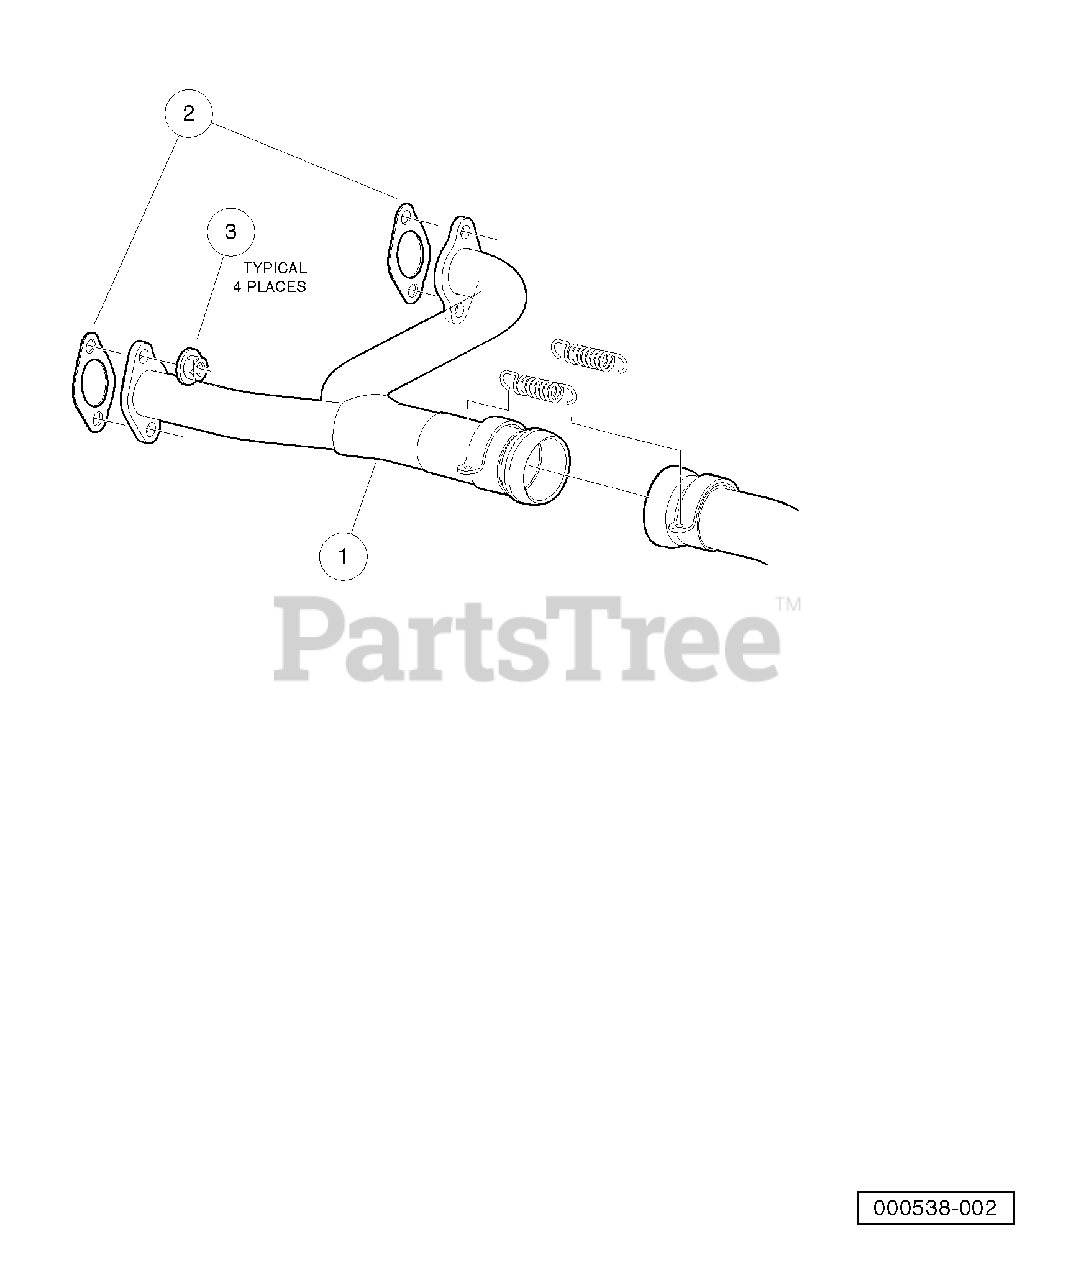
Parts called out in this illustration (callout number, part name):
1	Header, Exhaust, Gas
2	Gasket, Exhaust, Gx620
3	Nut Flg, M8 X 1.25 Serrated
